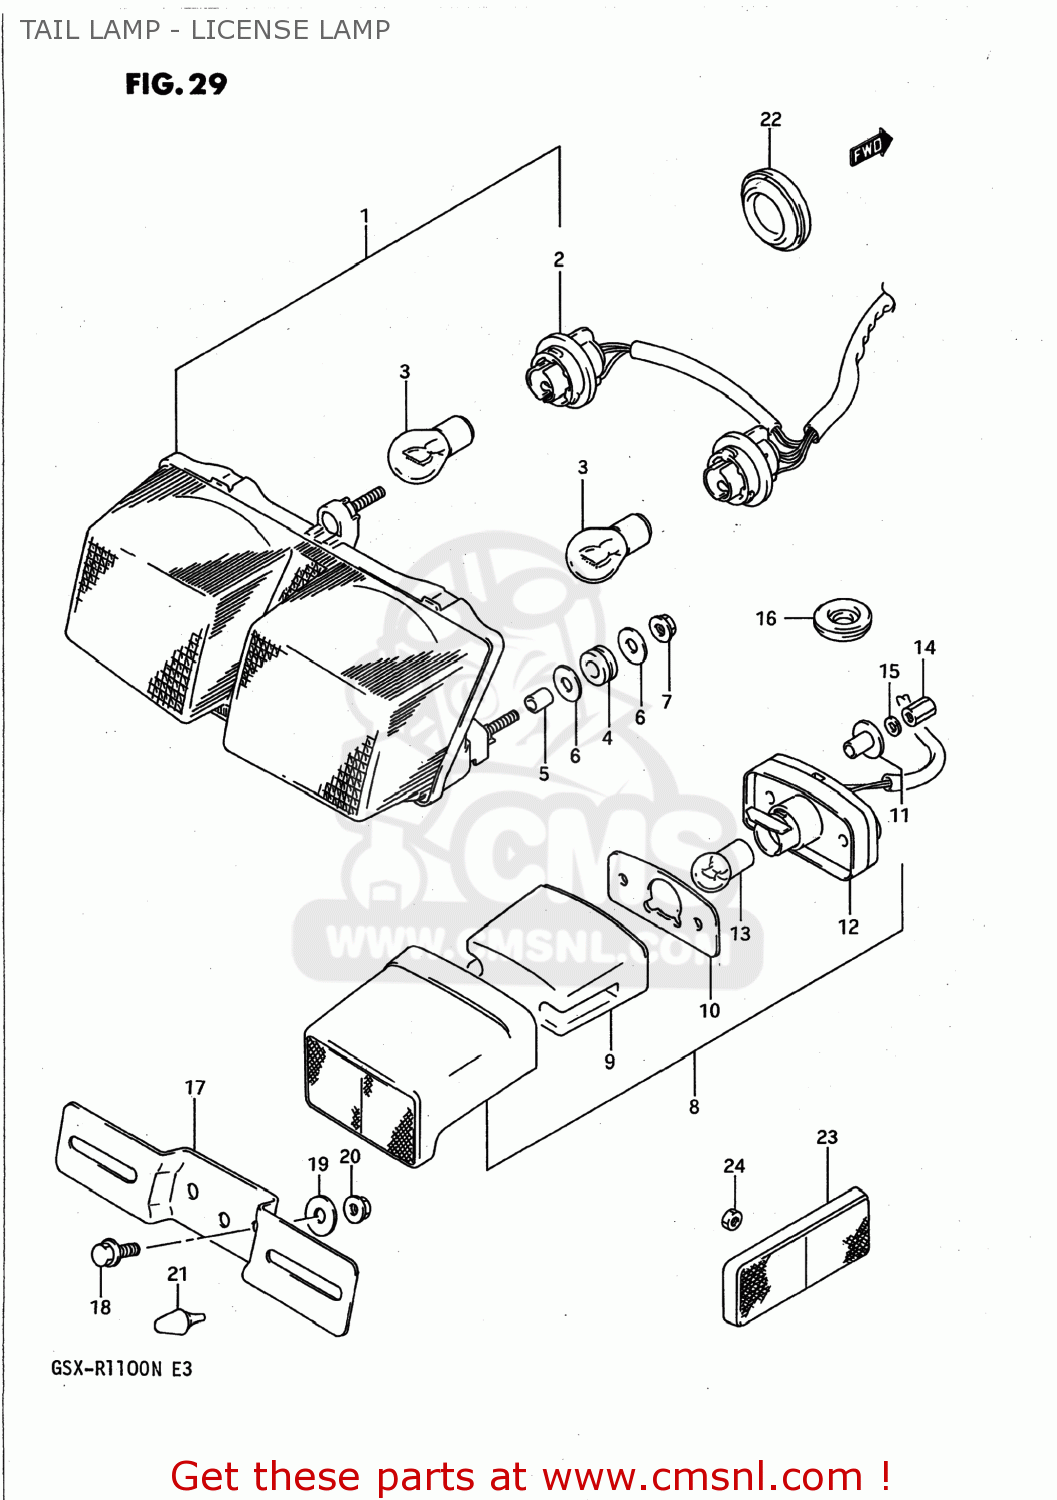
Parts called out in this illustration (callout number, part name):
1	LAMP ASSEMBLY,REAR COMBINATION
2	SOCKET ASSEMBLY
3	BULB(12V21/5W)
4	CUSHION
5	SPACER (6.1X8X9.5)
6	WASHER(6.5X18X1)
7	NUT
8	LAMP ASSEMBLY,LICENSE
9	LENS
10	GASKET,LICENSE LAMP (NAS)
11	SPACER
12	HOUSING,LICENSE
13	BULB
14	NUT
15	LOCK WASHER
16	GROMMET
17	BRACKET,LICENSE PLATE
18	BOLT
19	WASHER,COVER,FRONT
20	NUT
21	CUSHION
22	CAP OD:40
23	REFLECTOR ASSEMBLY,REAR
24	NUT 5MM
